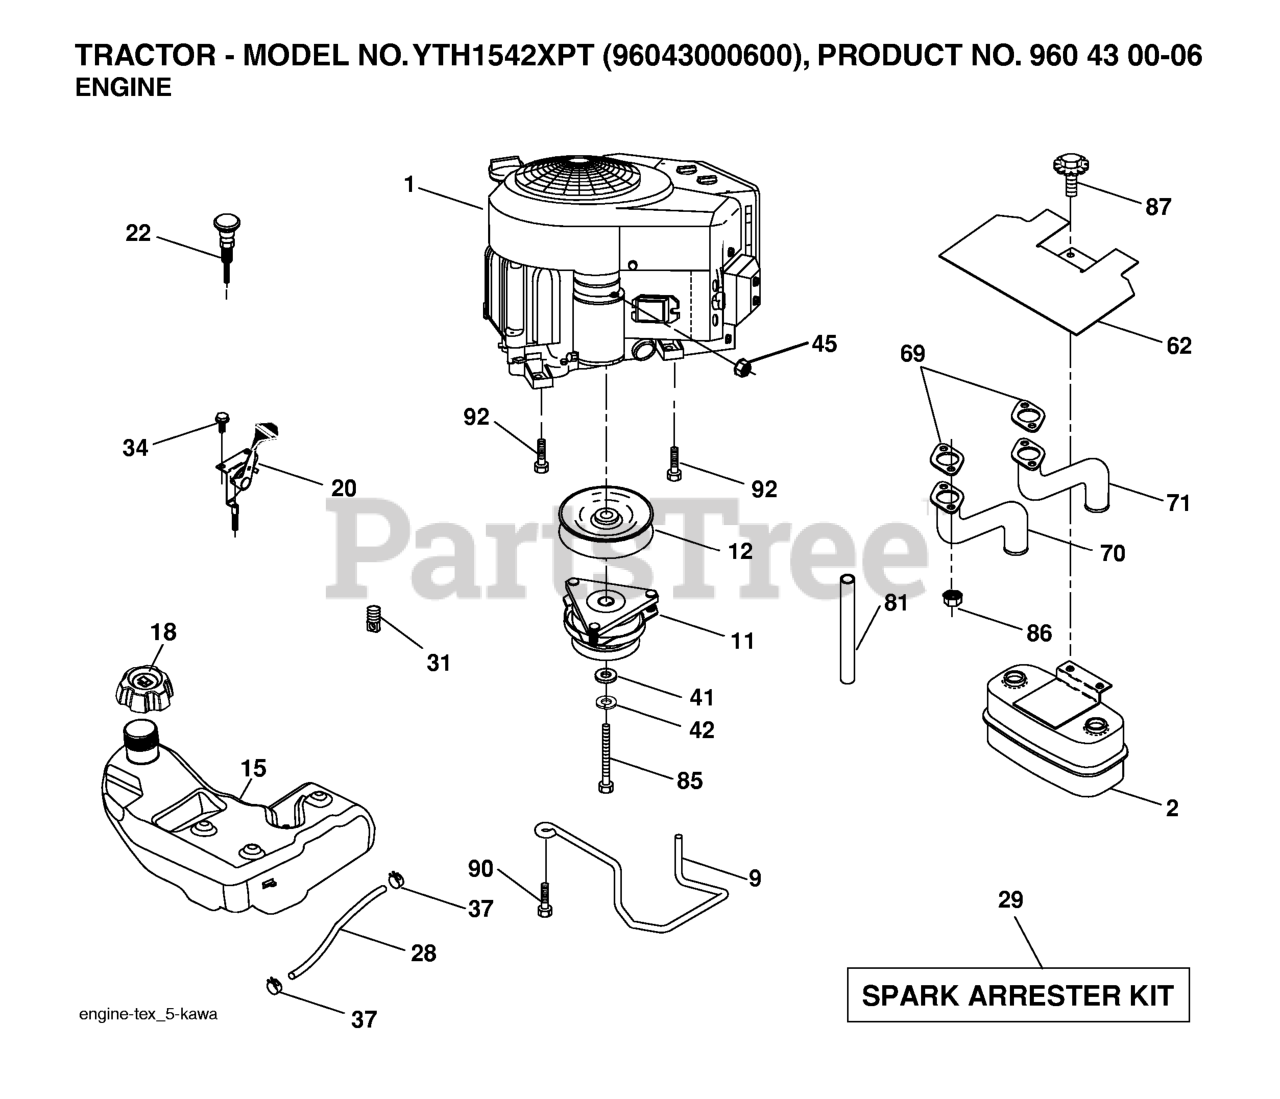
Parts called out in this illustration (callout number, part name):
2	MUFFLER.TWIN.CYL.LOW.TONE
9	KEEPER.BELT.ENGINE.3.25 (3 2)
11	RB.CLUTCH.OGURA.4.4.PD
12	PULLEY.ASM.ENG.OGURA.3
15	TANK.FUEL.4GAL
18	CAP.FUEL.TANK.3"GREY
20	THROTTLE CONTROL
21	SCREW
22	CONTROL, CHOKE
28	LINE.FUEL.64"REAR.EMIS
29	KIT.SPARK ARRESTOR 794945 B&S
37	HOSE CLAMP
42	LOCKWASHER
45	NUT
62	RP SHIELD HEAT MUFFLER
69	GASKET.MUFFLER
70	EXHAUST TUBE LH KAWI
71	EXHAUST TUBE RH KAWI
81	TUBE, DRAIN OIL ASM.
85	BOLT HEX 7/16-20X4-1/4"
86	NUT.HEX.FLANGE.TOPLOCK
87	BOLT.5/16-18UNCX1.W/SEMS.BLK
90	SCREW 3/8-16X1
92	SCREW 3/8-16X1
